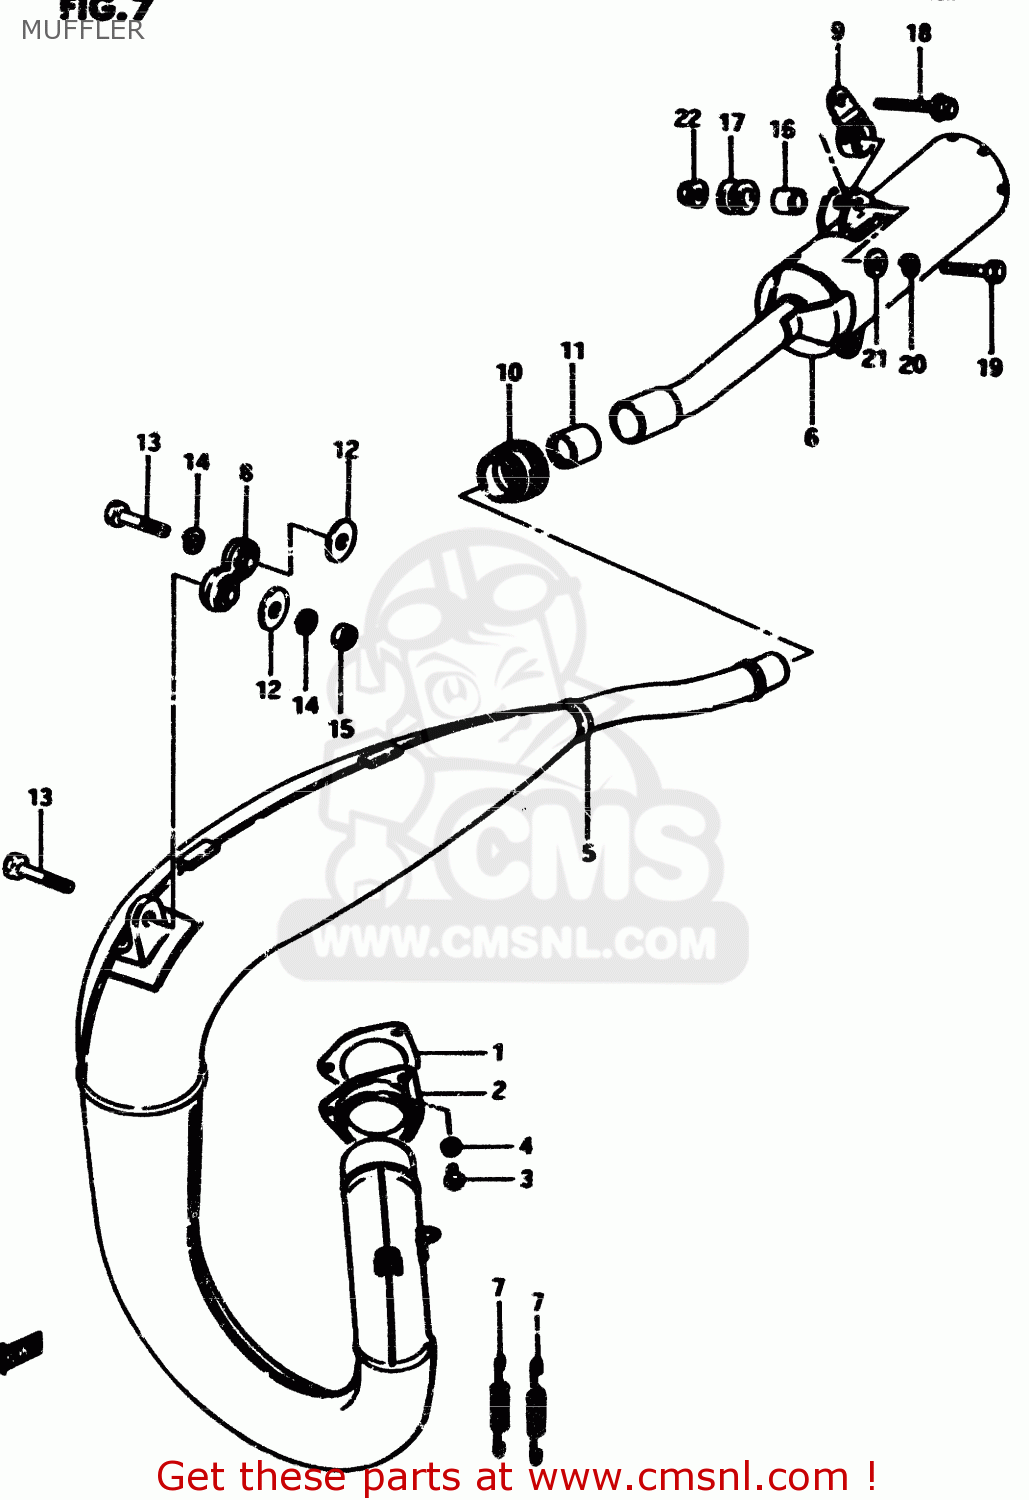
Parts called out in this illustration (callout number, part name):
1	GASKET,EXHAUST PIPE (MCA)
2	FLANGE,EXHAUST PIPE
3	SCREW
4	LOCK WASHER
5	MUFFLER, 1ST
6	MUFFLER, 2ND
7	SPRING
8	DAMPER,MUFFLER
9	DAMPER,MUFFLER SUPPORT
10	CONNECTOR,SECOND MUFFLER
11	GASKET,SECOND MUFFLER (NA) (NAS)
12	WASHER
13	BOLT(8X32)
14	LOCK WASHER
15	NUT 8MM
16	SPACER (8.6X12X17.5)
17	CUSHION
18	BOLT(8X25)
19	BOLT
20	LOCK WASHER
21	WASHER
22	NUT
